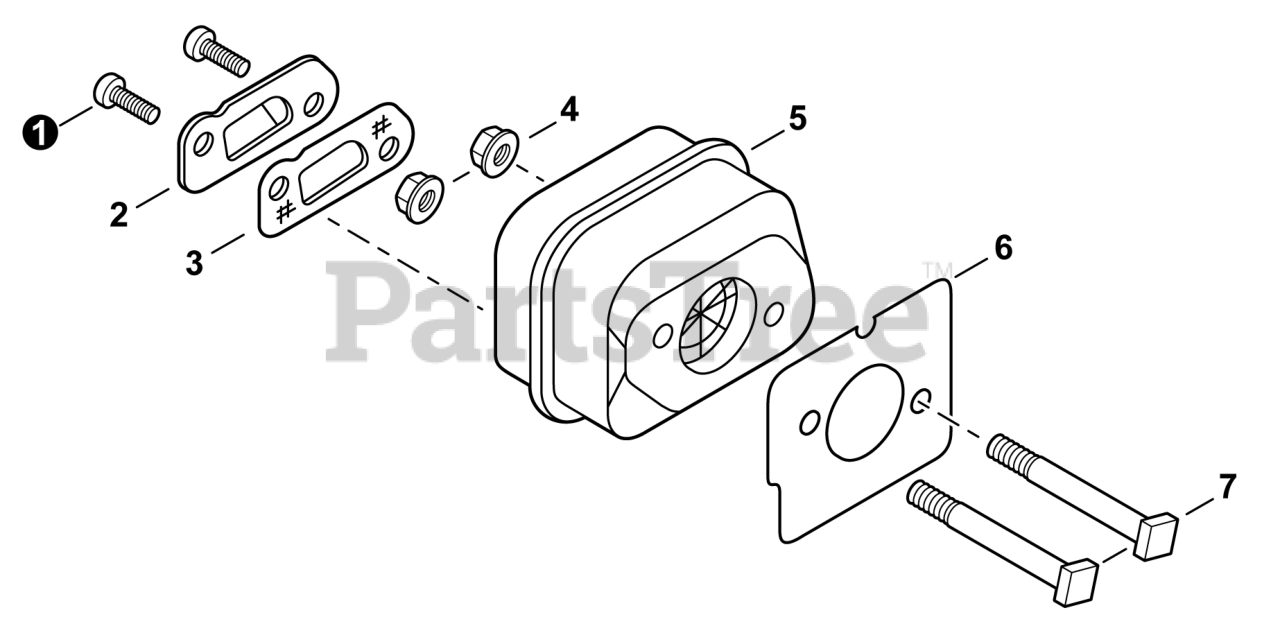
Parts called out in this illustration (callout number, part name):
1	BOLT, TORX 4x8
2	GUIDE, EXHAUST
3	SCREEN, SPARK ARRESTER
4	NUT, FLANGE M5
5	MUFFLER
6	GASKET, EXHAUST
7	BOLT 5x60
